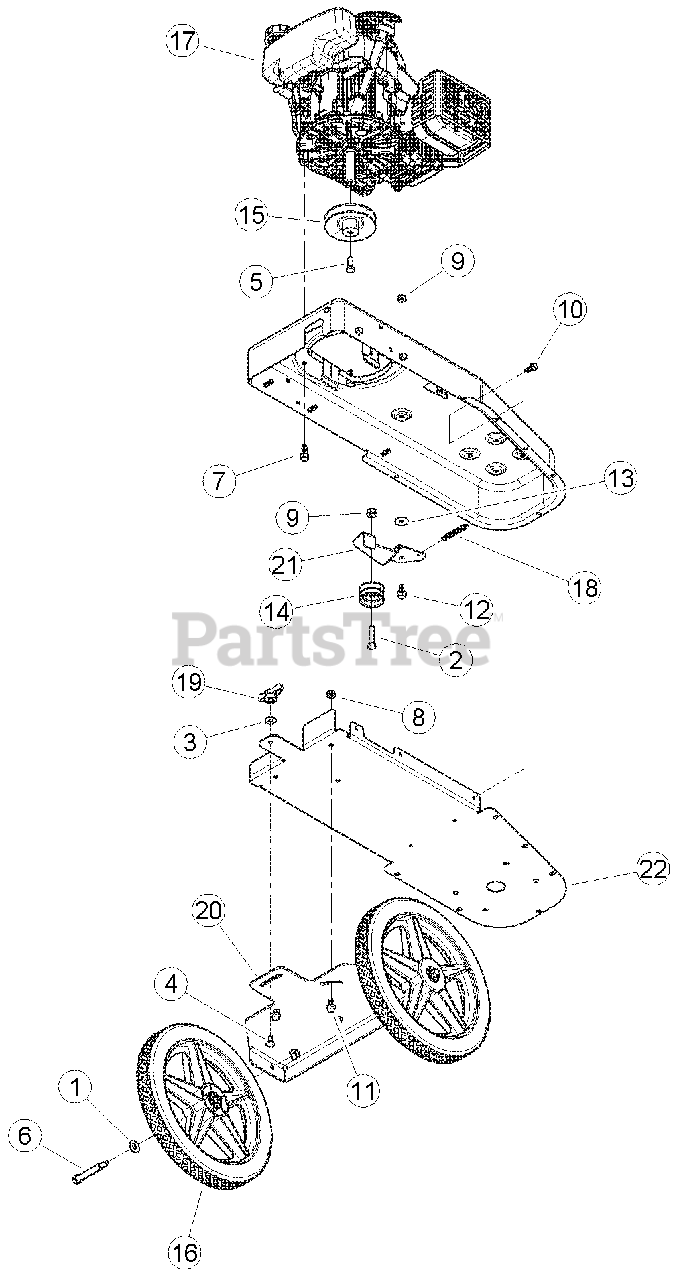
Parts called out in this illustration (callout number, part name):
1	WASHER, 1/2 SAE FLAT
2	BOLT, 3/8 X 1-3/4 HEX NC
3	WASHER, 5/16 FLAT
4	BOLT, 5/16 X 3/4 CRG
5	BOLT, 3/8 X 1 NF HEX GR8 ZP
6	BOLT, 3/8-16 X 3-1/4 FLANGE SHOULDER ZP
7	SCREW, 3/8-16 X 1 INZP THREAD ROLLING
8	NUT, 5/16-18 NYLOCK FLANGE
9	NUT, 3/8-16 NYLOCK FLANGE
10	SCREW, 5/16-18 X 1 IN ZP THREAD ROLLING
11	BOLT, 5/16-18 X 3/4 ZP FLANGE SHOULDER
12	BOLT, 5/16-18 X 3/4 FLANGE SHOULDER ZP
13	WASHER, 1.062 OD X .329 ID X .062 FLAT ZP
14	IDLER, 1-7/8 DOUBLE FLANGE
15	PULLEY, 4.0 X 7/8 BOREB GROOVE CAPPED
16	WHEEL, 14 X 1.75 TRIMMER
17	ENGINE, SUBARU EA190V (FOR SERVICE CONSULT ENGINE OWNER'S MANUAL OR YOUR NEAREST AUTHORIZED SUBARU INDUSTRIAL ENGINE DEALER.)
18	SPRING, IDLER EXTENSION
19	KNOB, 5/16-18 UNC TEE
20	PLATE, TRIMMER AXLE
21	BRACKET, IDLER ENGAGEMENT
22	PLATE, TRIMMER BASE
